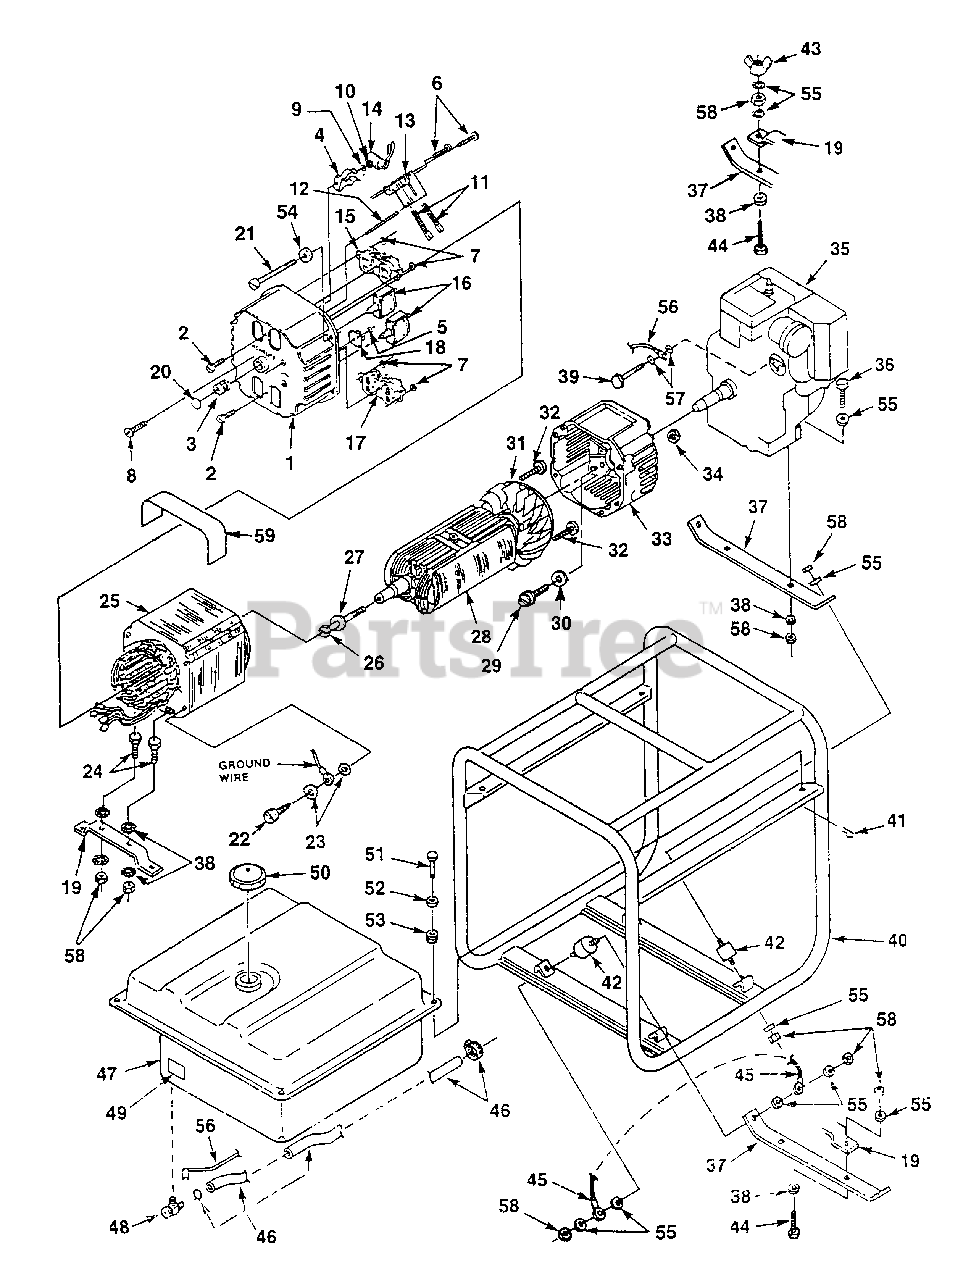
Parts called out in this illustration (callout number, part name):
1	BRUSH HEAD- Complete
2	SCREW- Mach. Pan Hd. (6-32 x 1/2")
3	BEARING- Needle
4	CLIP- Spring
5	WASHER- Shaft Retention
6	SCREW- Pan Hd (6-19 x 3/4")
7	WASHER- Shaft Retention
8	SCREW- Mach. Pan Hd. (6-32 x 3/4")
9	WASHER- Lock Ext. (#6)
10	NUT- Hex
11	BRUSH
12	PIN- Retainer
13	HOLDER- Brush
14	CAPACITOR W/Lead
15	RECEPTACLE- Duplex (NEMA 5-15R)
16	BREAKER-Circuit (25 AMP)
17	RECEPTACLE- 240V (NEMA 6-20R)
18	RECTIFIER
19	BRACKET- Generator Mounting
20	PLUG- Expansion
21	BOLT- Stator
23	WASHER- Lock (Int./Ext.)
24	SCREW (5/16 x 3/4")
25	STATOR & CORE
26	BOLT- Rotor
27	WASHER- Lock (5/16")
28	ROTOR & CORE
29	SCREW- Cap Hex Hd.
30	WASHER- Lock (Int./Ext.)
31	FAN ASSEMBLY
32	SCREW- Pan Hd.
33	END BELL
34	NUT- Hex Locking
35	ENGINE
36	SCREW- Cap Hex Hd.
37	SUPPORT- Engine
38	WASHER (Ext./Int.)
40	ROLL CAGE
41	PIN- Cotter
42	ISOLATOR- Vibration
43	NUT- Wing
44	SCREW- Mach. Hex Hd.
45	GROUND STRAP
46	FUEL LINE ASSEMBLY
47	FUEL TANK
48	VALVE- Fuel
49	DECAL- Fuel Valve
50	CAP- Fuel
51	PIN- Clevis
52	WASHER- Flat
53	GROMMET- Isolator
54	WASHER- Flat
55	WASHER- Lock (Int.)
56	GROUND STRAP
57	WASHER- Lock
58	NUT- Hex (5/16-18)
59	DECAL- Stator
